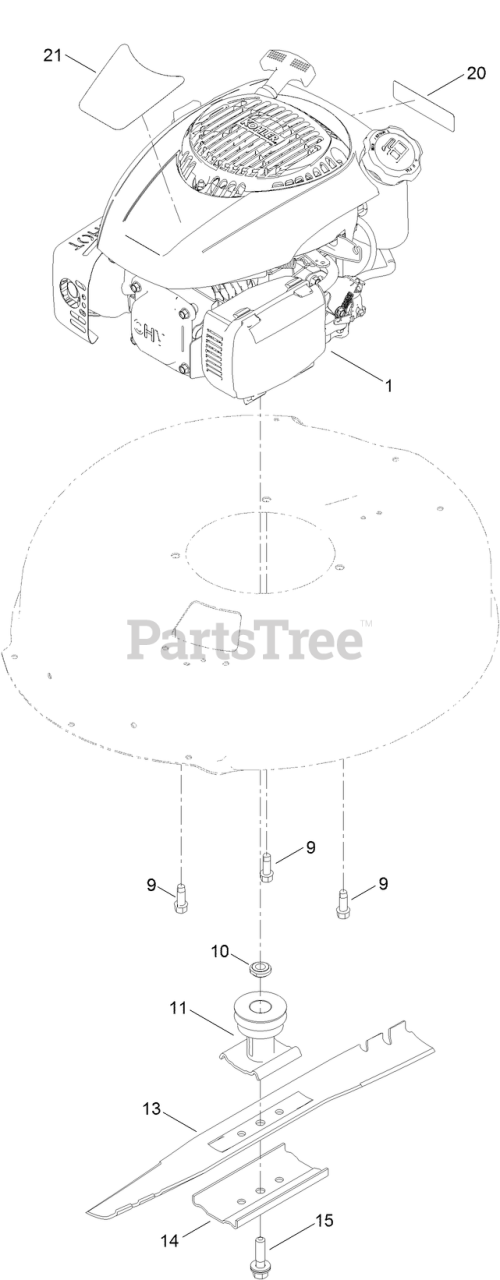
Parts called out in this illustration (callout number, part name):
9	SCREW-TAPTITE
10	SPACER-DRIVER
11	DRIVER-BLADE
14	SUPPORT-BLADE
15	BOLT-BLADE
20	DECAL-ARRESTOR, SPARK
21	DECAL-SHROUD
